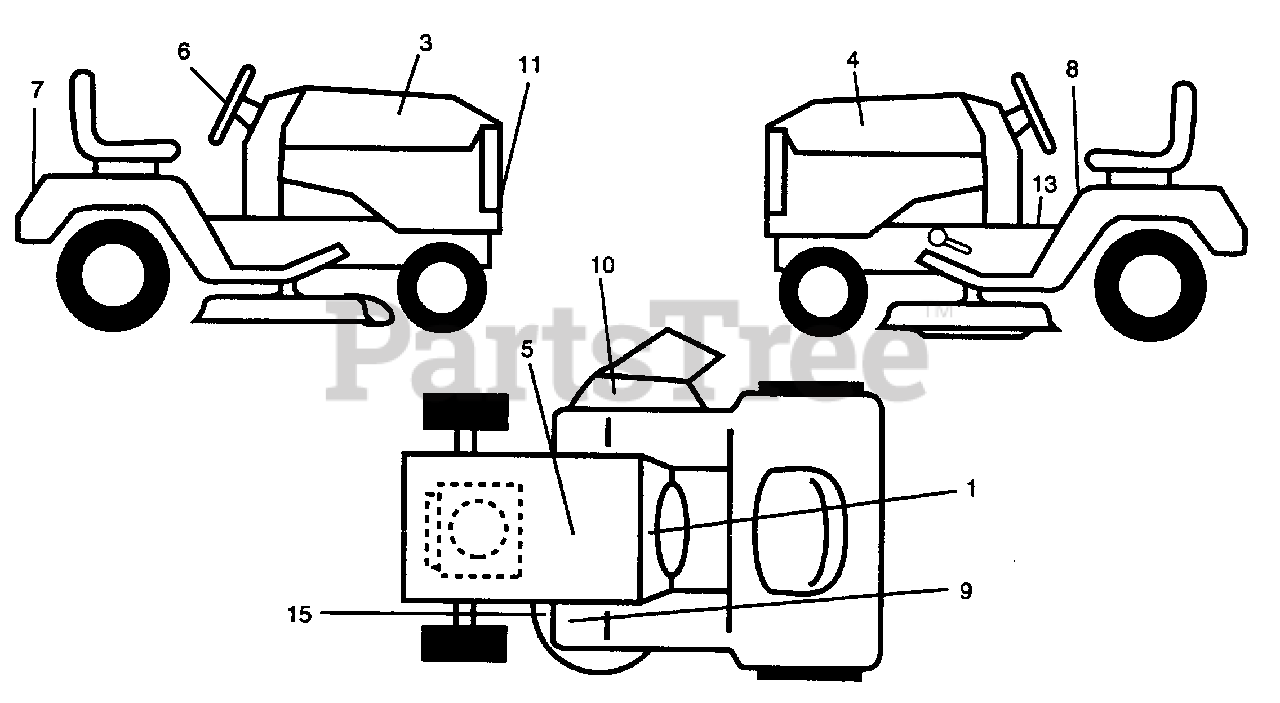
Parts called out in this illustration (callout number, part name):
1	Decal Instruction Dash Eng/fr
3	Decal Hood RH
4	Decal Hood LH
5	Decal Bat Dan/Poi P/L Symbols
6	Decal Insert Steering Wheel
8	Decal Caution Fender Eng/fr
9	Decal Clutch/brake Eng/fr
10	Decal Warning MULT-LANGUAGE
13	Decal Brake Parking Saddle
15	Decal V-Belt Sch 44/50
